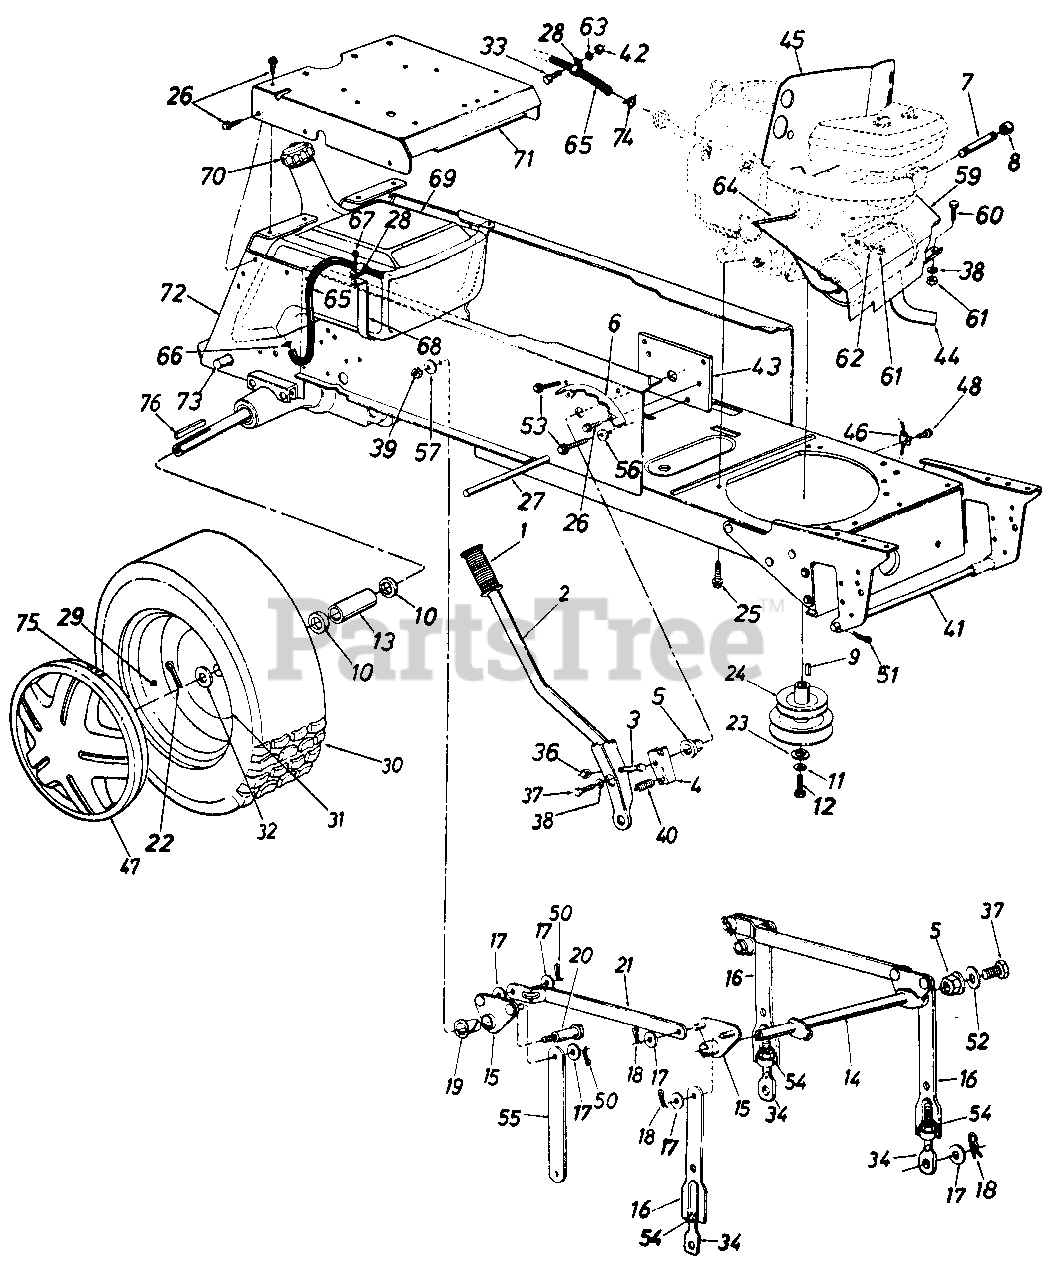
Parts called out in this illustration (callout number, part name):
1	Grip
2	Lift Handle Ass'y.
3	Hex Bolt 5/16-18 x 1.5" Lg.
4	Lift Shaft Drive
5	Plastic Hex Brg. 5/8" I.D.
8	Pipe Cap 3/8-18 Npt.
9	Sq. Key 1/4" x 1/4" x 1.50" Lg.
10	Fl-Wash. 1.03" I.D. x 1.62" O.D.
11	L-Wash. 7/16" I.D.
12	Hex Scr. 7/16-20 x 1.50" Lg.
13	Spacer 1.0" I.D. x 1.25" O.D.
14	Lift Shaft Ass'y.
15	Lift Pivot Brkt. Ass'y.
17	Fl-Wash. 1/2" I.D. x 1.00" O.D. x .090"
18	Hairpin Cotter
19	Nyliner 5/8" I.D. x .88" Lg.
20	Shld. Bolt 518" Dia. x .96" Lg. 3/8-16
23	Flat Wash. .44" I.D. x 1.25" O.D. x .17"
24	Two-Step Engine Pulley
25	Hex Wash. Hd. Scr. 3/8-16 x 1.25" Lg.
26	Hex Thd. Rolling Scr. 5/16-18 0 x.75" Lg.
27	Running Board Rod
29	Air Valve
33	Hex Bolt 1/4-20 x .62" Lg.
34	Eye Bolt Adj. Link 1/2-13 Thd.
36	Hex Cent. L-Nut 5/16-18 Thd.
37	Hex Scr. 5/16-24 x .62" Lg.
38	L-Wash. 5/16' I.D.
39	Hex Top L-Nut 3/8-16 Thd.
40	Compression Spring
41	Deck Connecting Rod
42	Hex Nut 1/4-20 Thd.
45	Heat Shield
46	Mounting Clamp
48	Hex Wash. Hd. TT-Tap Scr. 1/4-20 x .5" Lg.
50	Cotter Pin .09 Dia. x 1.0" Lg.
51	Int. Cotter Pin
52	Flat Washj.34" I.D. x 1.12"
53	Hex Wash. Hd. AB-Tap Scr. 5/16-24 x .5" Lg.
54	Hex Nut 1/2-13 Thd.
56	Fl-Wash..344" I.D.
57	Bell-Wash. .4" I.D. x 1.13" O.D.
59	Front Heat Shield
60	Hex Bolt 5/16-18 x .75" Lg.
61	Hex Nut 5/16-18 Thd.
62	L-Wash. 5/16" I.D.
63	L-Wash. 1/4" I.D.
64	Trim Strip 10" Lg.
65	Fuel Line 50" Lg.
67	Hex AB-Tap Scr. 1/4 x .62" Lg.
68	Fuel Tank Strap
69	Gas Tank
70	Gas Gauge
71	Seat Plate
75	Spring Clip
76	Sq. Key 1/4" x 3" Lg.
